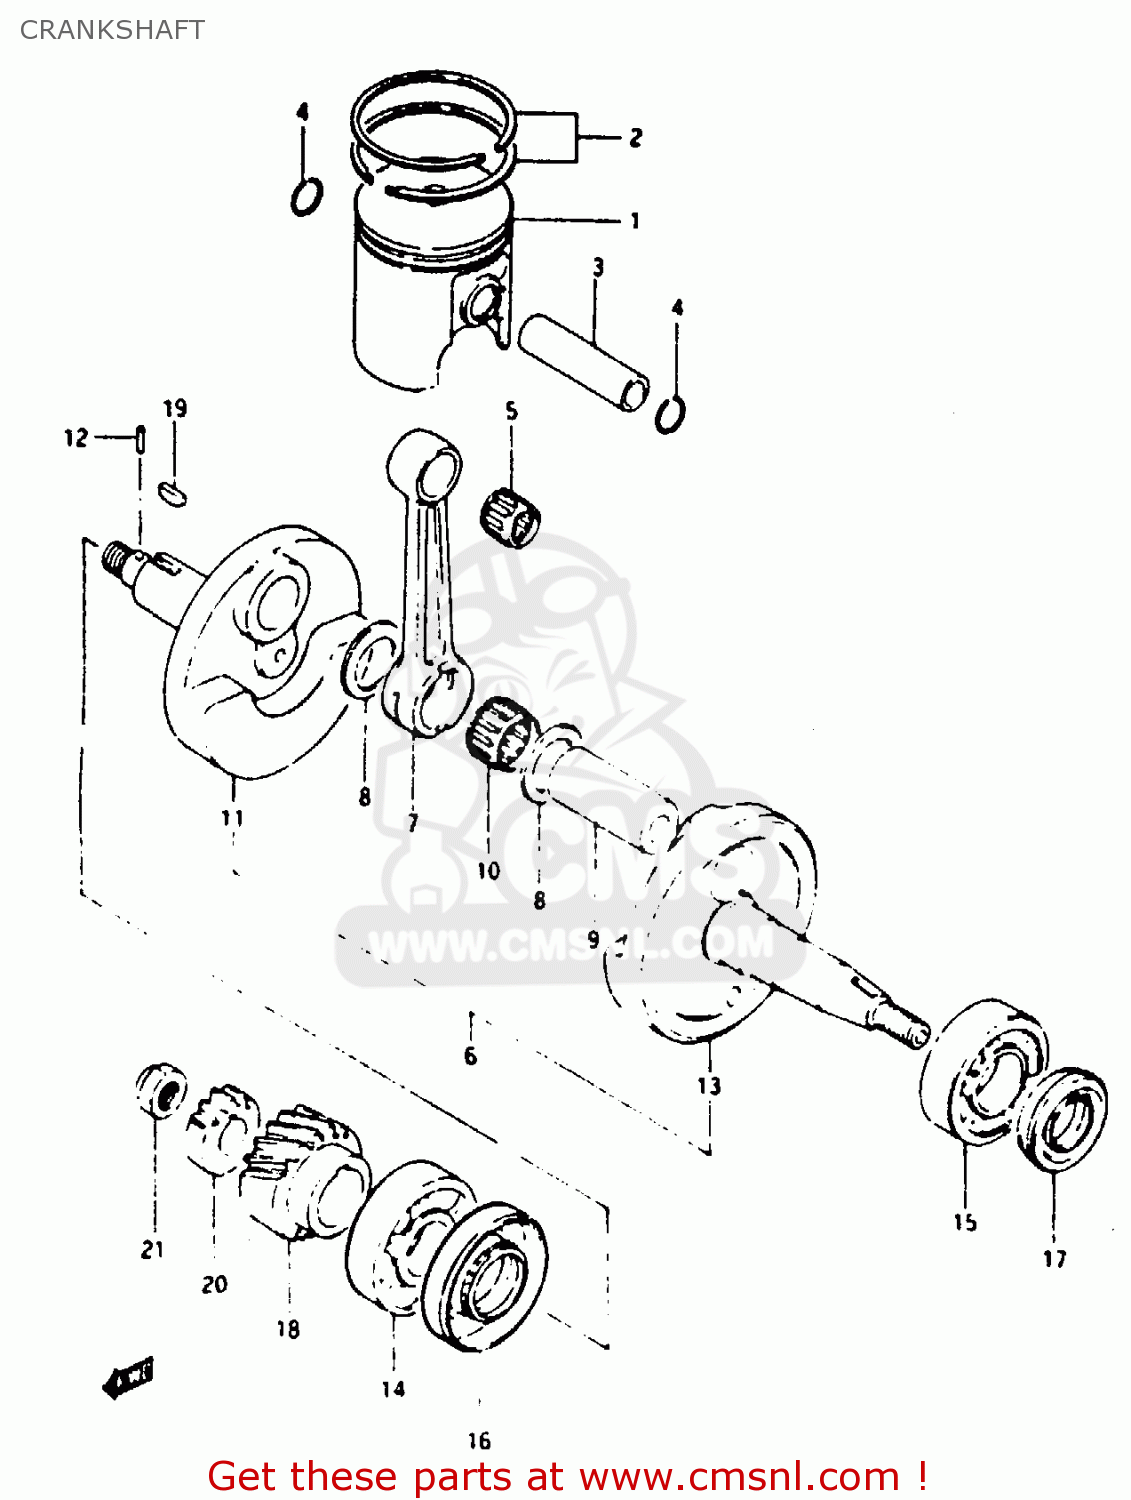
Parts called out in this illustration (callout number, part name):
1	PISTON (OS:0.5)
2	RING SET, PISTON (STD)
3	PIN,PISTON
4	RING,SNAP 14MM
5	BEARING 14X18X19.8
6	CRANKSHAFT ASSY
7	ROD,CONNECTING
8	WASHER(22X35X1)
9	PIN,CRANK
10	BEARING(22X28X16)
11	CRANKSHAFT, RH
12	PIN 3X5
13	CRANKSHAFT, LH
14	BEARING
15	BEARING(25X52X15)
16	SEAL,OIL(28X56X7)
17	SEAL,OIL(19.6X37X8)
18	GEAR, PRIMARY DRIVE (NT:18)
19	KEY
20	GEAR, WATER PUMP DRIVE
21	NUT
